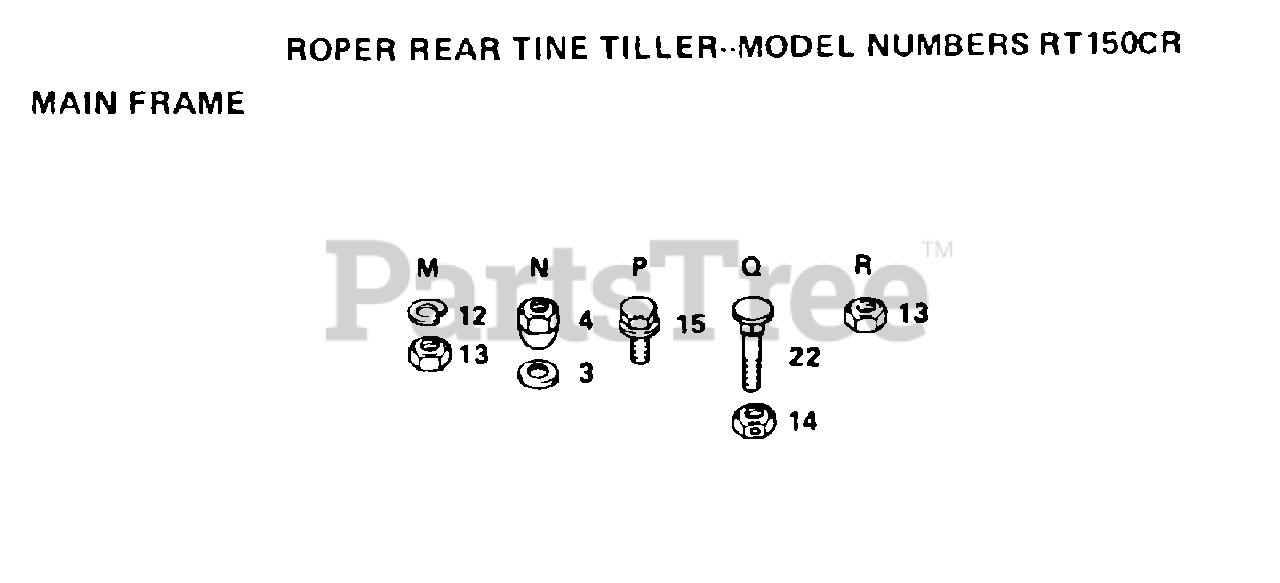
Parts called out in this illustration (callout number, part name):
3	WASHER
4	NUT TI
12	LOCKWASHER
13	NUT.HEX.3/8-16UNC
15	SCREW TI
